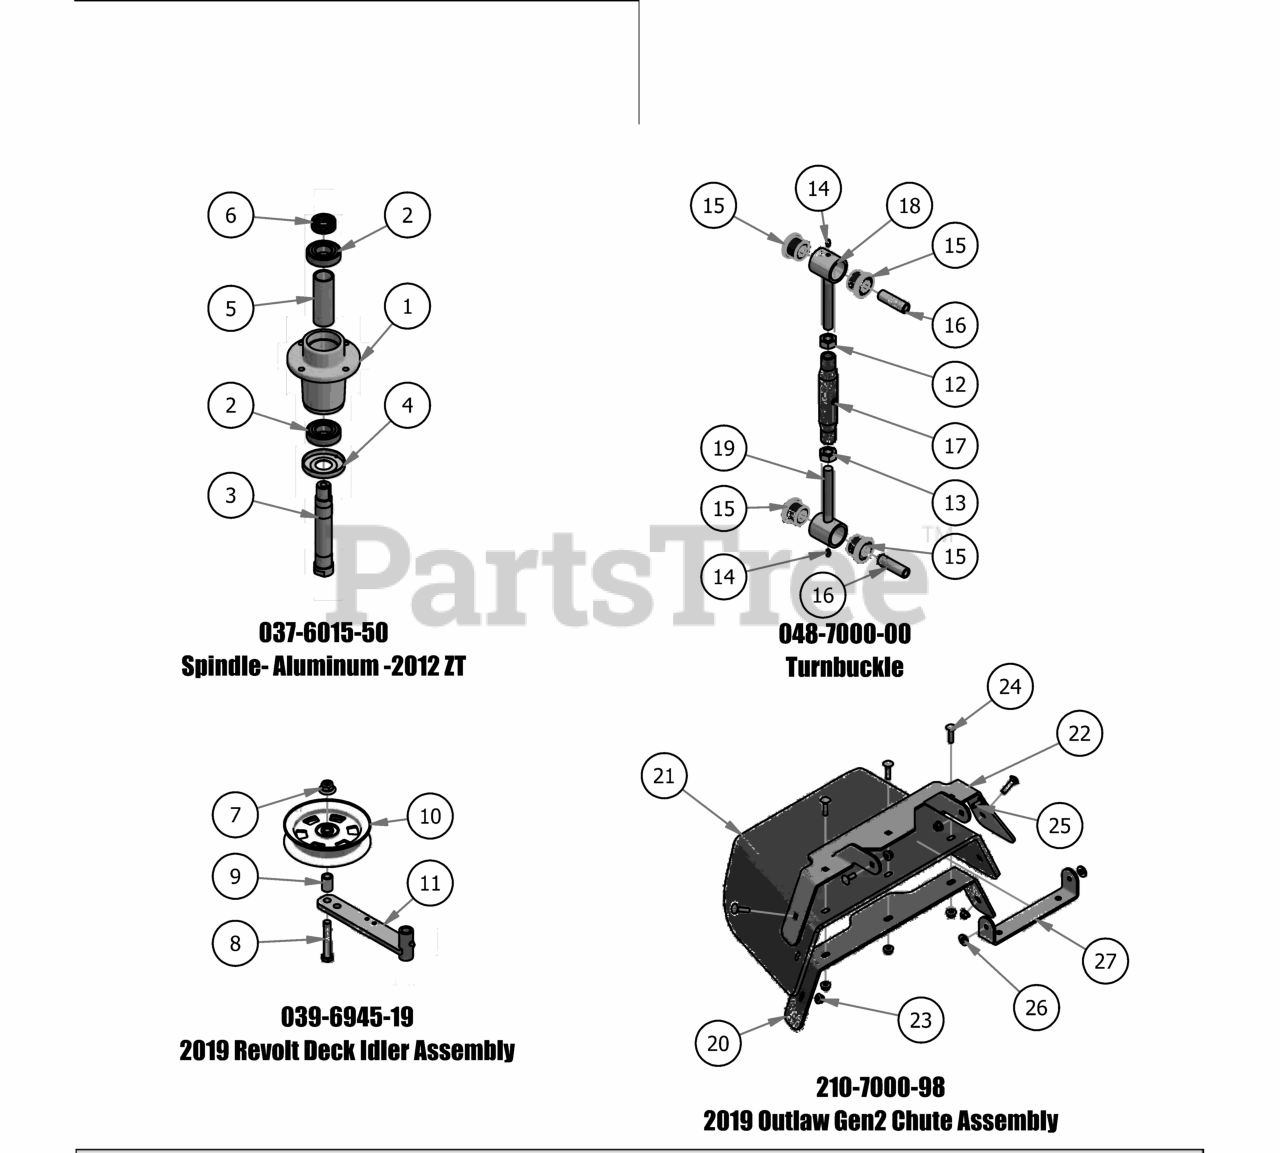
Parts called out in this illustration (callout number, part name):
1	Aluminum Spindle Housing -2010
2	Spindle Bearing, 2004 and up
3	Short Spindle Shaft w/Locking
4	Dust Cover
5	Tube Spacer for Spindle Shaft
6	Collar Spacer - Top of Spindle
7	1/2-13 Nylon Flange Nut
8	1/2-13 x GR 5 Hex Bolt Zinc
9	.502 x .750 x 1.25 Length Spacer
10	5" Idler Pully
11	Deck Idler
12	Hex Nut, 11/16-12
13	Hex Nut, 11/16-12 Left Handed
14	1/4" Press in Grease Fitting
17	2015 Outlaw Turnbuckle Body
18	Right-Handed End
19	Turnbuckle End Left-Handed Thread
20	2019 Lower Chute Bracket
21	2019 Belted Chute with Logo
22	2019 Upper Chute Bracket
23	5/16" Nylon Flange Nut
24	5/16" x 1 1/4" Carriage Bolt
25	5/16" x 7/8" Carriage Bolt
26	.360 ID Plastic Washer
27	2019 Chute Hanger
